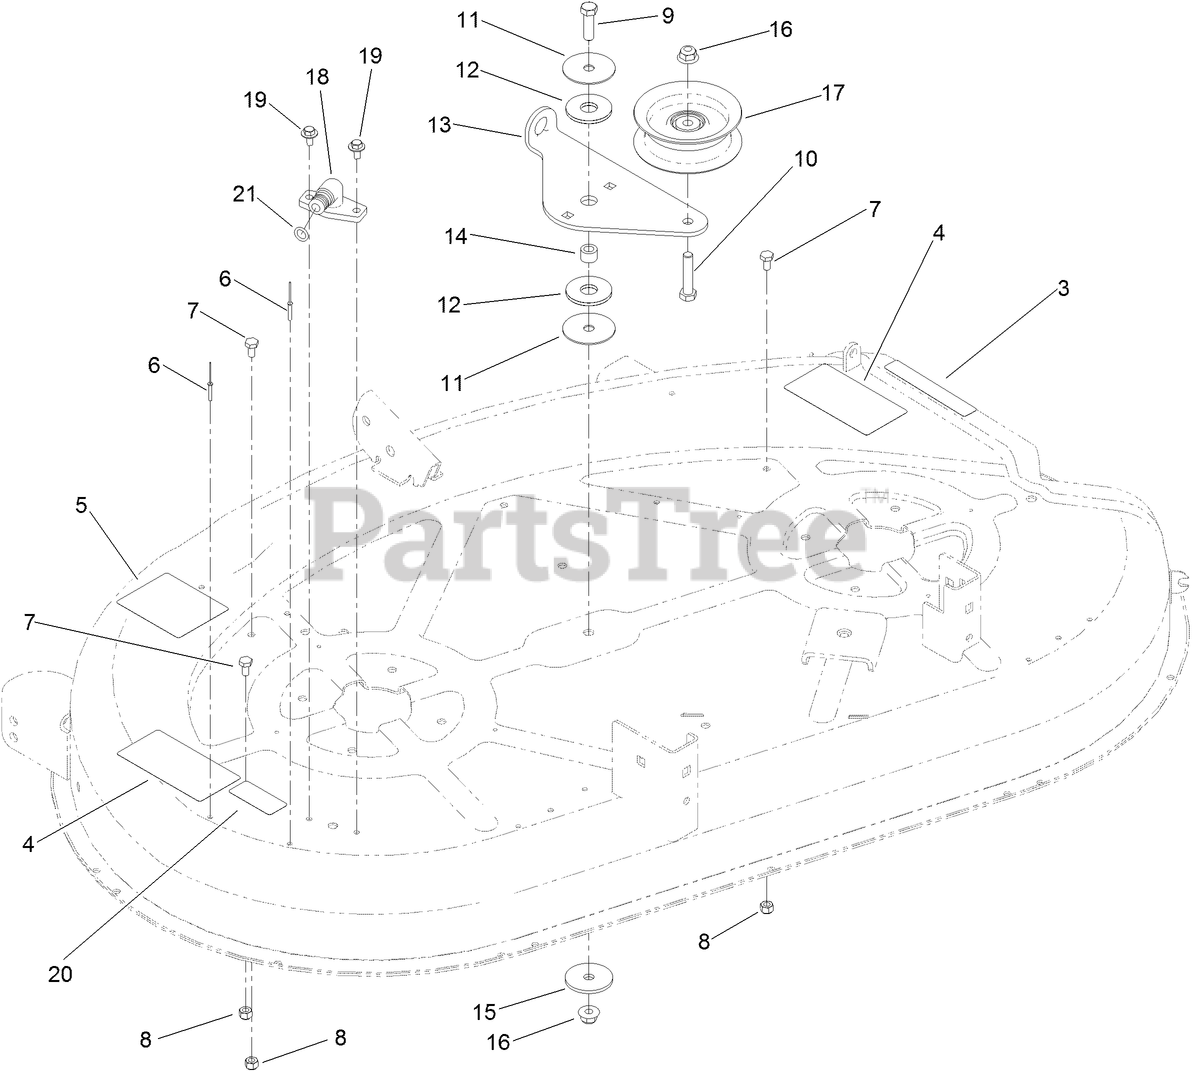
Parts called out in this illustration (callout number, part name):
3	DECAL-DANGER
4	DECAL-DANGER, DECK
5	DECAL-ROUTING, BELT
6	RIVET-BLIND
7	SCREW-HH
8	NUT-LOCK, NI
9	SCREW-HH
10	SCREW-HH
11	WASHER
12	WASHER-FRICTION, COMPOSITE
13	ARM-IDLER
14	SPACER
15	WASHER-REBOUND
16	NUT-HF, NI
17	PULLEY-IDLER, FLAT
18	FITTING-WASHOUT
19	SCREW-HHFTF
20	DECAL-SERVICE
21	O-RING
